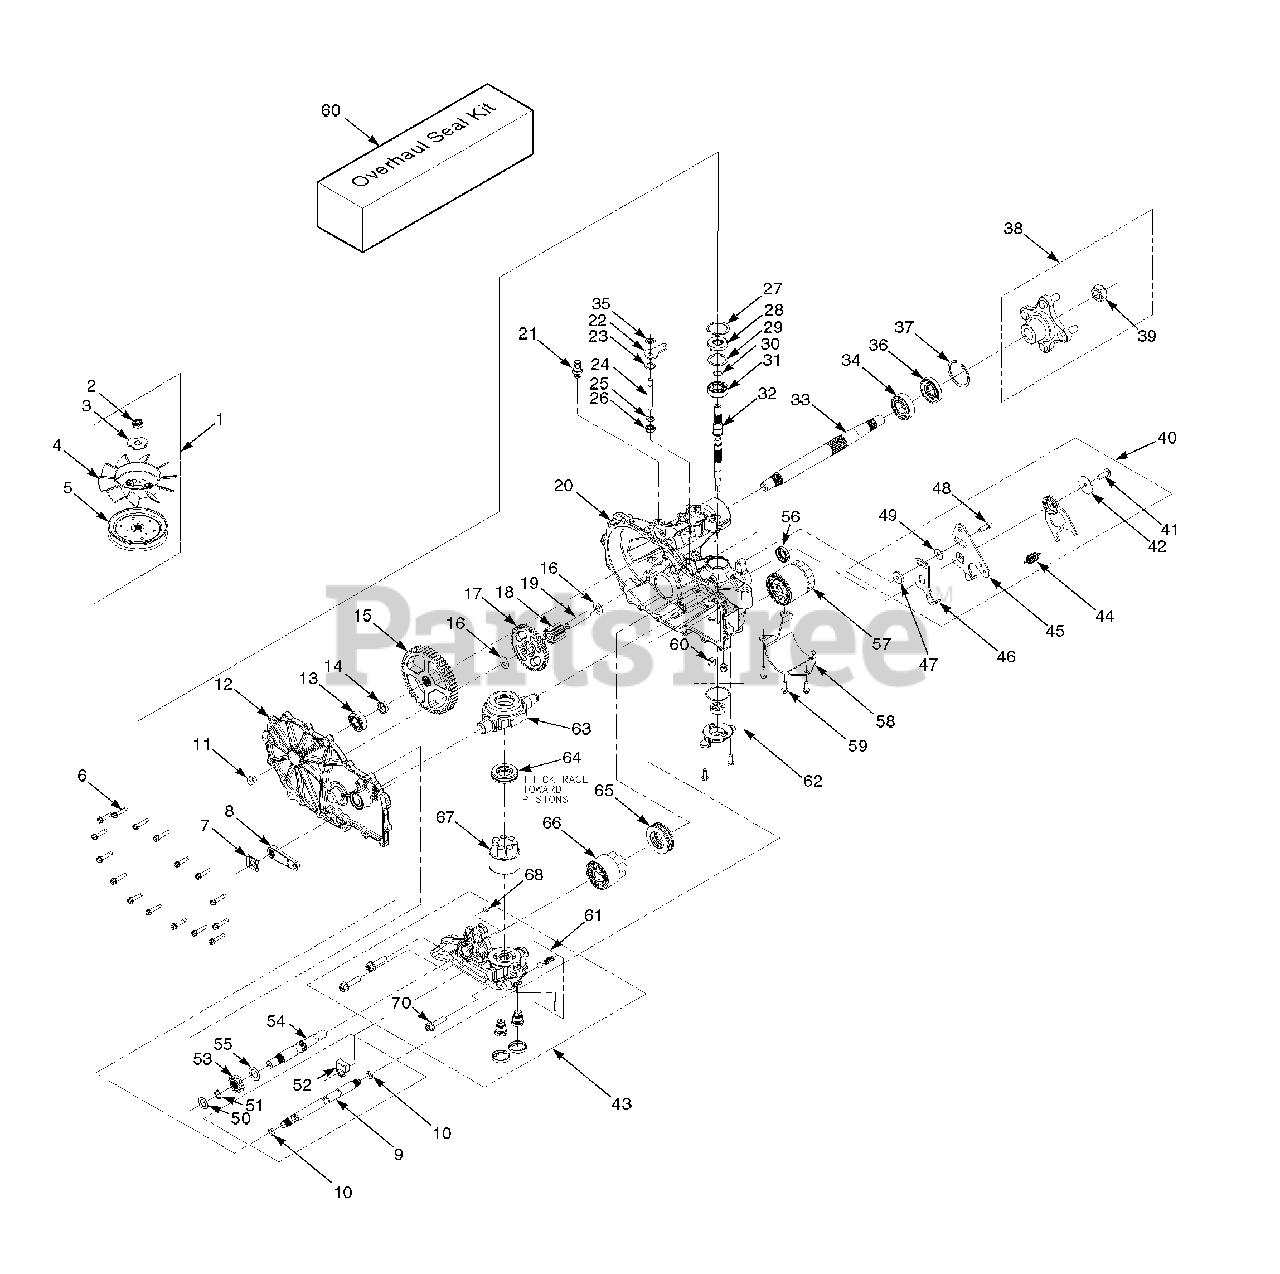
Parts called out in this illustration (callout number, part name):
1	Kit, Fan & Pulley
2	Nut, Hex Locking 1/2-20
3	Washer, Slotted
4	Fan, 7" Dia.
5	Pulley, Cupped 4-1/2" Dia.
6	Bolt, Hex Head 1/4-20 x 1-1/4"
7	Clip, Retaining
8	Handle, Brake
9	Shaft, Brake
10	O-Ring
11	Plug, 9/16-18
12	Kit, Side Cover RH
13	Bearing, Ball .75 x 40 x 12
14	Spacer, .75 x 1.0 x .257
15	Gear, 54T
16	Washer, .5 x 1.0 x .03
17	Gear, 45T
18	Gear, 11T Steel
19	Jackshaft Pin
20	Kit, Housing RH
21	Fitting
22	Arm, Bypass
23	R i n g , Retaining .750 Internal
24	Rod, Bypass
25	Ring, Retaining .375 External
26	Seal, Lip .375 x .75 x .25
27	R i n g , Retaining 2.06 Internal
28	Seal, Lip 17 x 40 x 7
29	Washer, 1.23 x 1.56 x .04
30	Ring, Retaining Wire
31	Bearing, Ball 17 x 40 x 12 Open
32	Shaft, Input
33	Shaft Kit, Axle
34	Bearing, Ball 1.0 x 52 x 15 Open
35	Ring, Retaining .375 External
36	Seal, Lip 25 x 52 x 10 TC Gray
37	R i n g , Retaining 2.06 Internal
38	Kit, Hub
39	Nut, Hex Locking 3/4-16
40	Kit, RTN Assembly
41	Bolt, 5/16-24 x 1" Patch
42	Washer, .343 x 1.5 x .062
43	Kit, Center Section RH
44	Spring
45	Arm, Control
46	Arm, Neutral RH
47	Spacer, .320 x 1.005 x .179
48	Bolt, 5/16-24 x 1" Patch
49	Washer, .34 x .88 x .06
50	Washer, .63 x 1.0 x .05
51	Ring, Retaining
52	Pawl, Brake
53	Gear, 14T Steel
54	Shaft, Motor
55	Washer, .72 x 1.16 x .04
56	Seal, Lip 18 x 32 x 7
57	Filter
58	Filter Guard
59	Bolt, 1/4-20 x 3/4"
60	Seal Kit
61	Kit, Charge Relief
62	Kit, Charge Pump
63	Trunnion Swashplate
64	Thrust Bearing
65	Thrust Bearing
66	Kit, Motor Cylinder Block
67	Kit, Cylinder Block
68	Plate, Bypass
69	Kit, Charge Relief
70	Bolt, Hex Head 3/8-16 x 1-1/2" Patch
